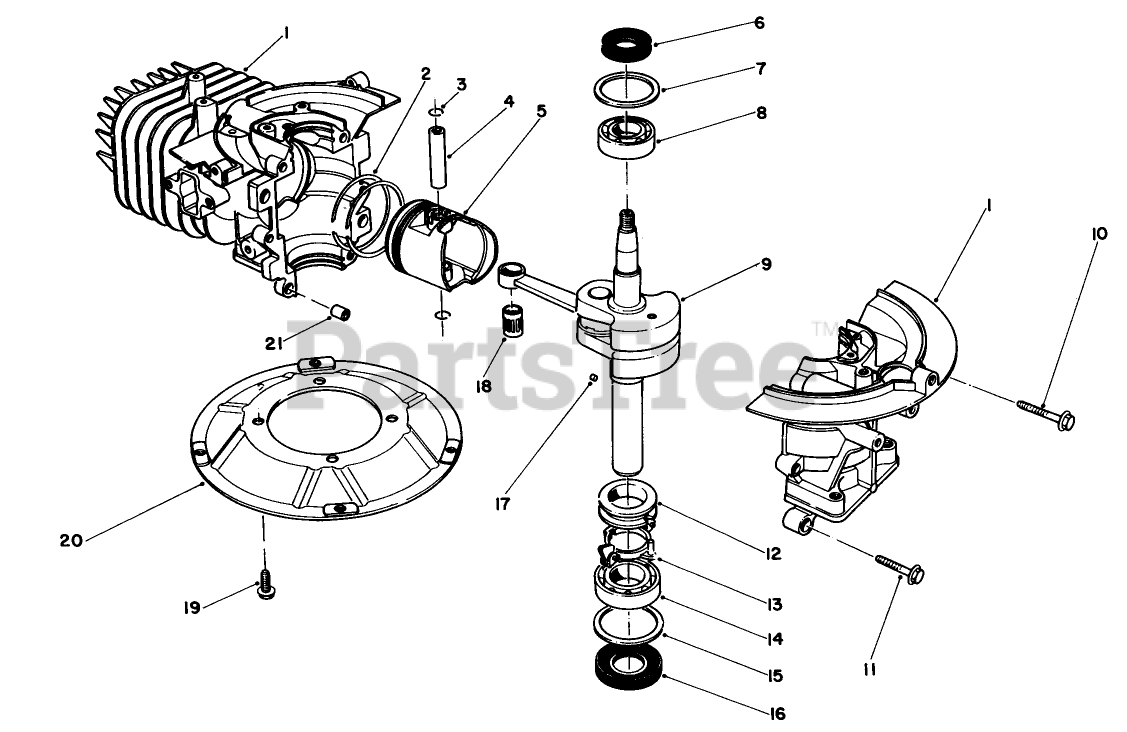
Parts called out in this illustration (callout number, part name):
2	RING SET
4	PIN-PISTON
6	OIL SEAL
7	WASHER-UPPER
8	BEARING-UPPER
12	SPACER
13	BRACKET
14	LOWER BRG
15	WASHER-LOWER
16	SEAL-OIL
18	BEARING
20	PLATE-MOUNTING
